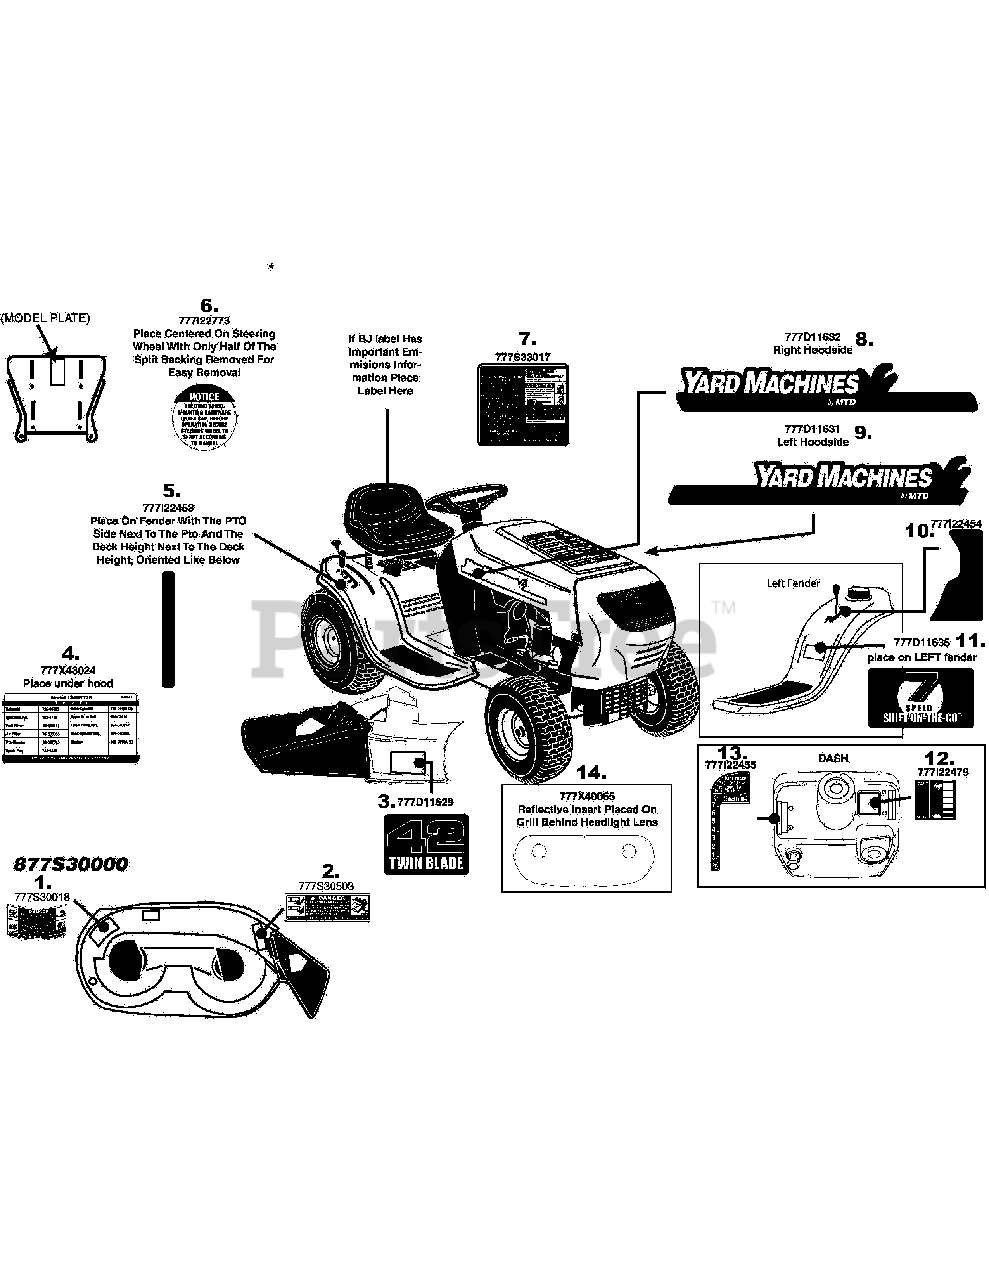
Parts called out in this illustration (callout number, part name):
1	LABEL-DECK SAFETY
2	LABEL-DANGER CHUTE
3	LABEL-RIDER DECK YARD MACHINE 42"
4	LABEL-RIDER PARTS LIST 13AN772G
5	LABEL:RIDER LT-5 FENDER
6	LABEL-RIDER:SECURE WHEEL
7	LABEL-LT 5 TRANS COVER NO OCR
8	LABEL-RIDER HOOD RH YARD MACHINE
9	LABEL-RIDER HOOD LH YARD MACHINE
10	LABEL:RIDER LT-5 FENDER
11	LABEL-RIDER FENDER YARD MACHINE
12	LABEL: RIDER LT-5 THRT/CHK
13	LABEL:RIDER LT-5 DASH
14	LABEL REFLECTOR
